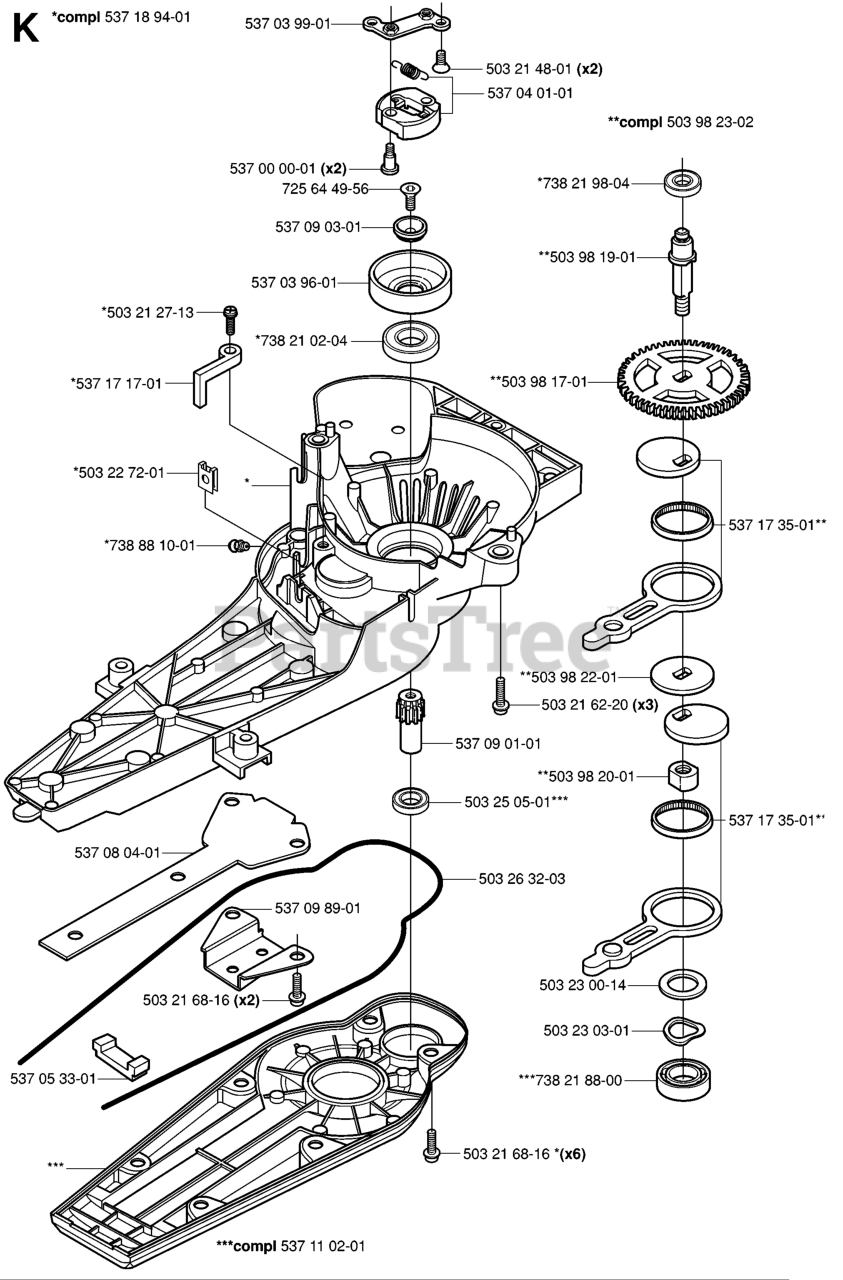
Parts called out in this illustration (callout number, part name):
1	DECK ASSY-WELDMENT
2	RP BOLT 5/16-18 X3/4 ZN/YEL GR
3	BRKT ASM SWAY BAR
4	BRKT DECK SW BAR
5	RETAINER-SPRNG RB
6	REAR SUSP ARM
8	BLADE BOLT
9	LOCKWASHER
10	WASHER.BLADE
11	BLADE 38" V MULCH
12	BEARING.BALL.#6204.(MANDREL)
13	SHAFT ASM VENT
14	HOUSING.MANDREL.VENTED (MACHD)
16	STRIPPER
19	BOLT SHD 5/16-18
21	LOCKNUT
23	BRACKET, DEFLECTOR
24	CAP-SLEEVE LT
25	SPRING TORSION
26	NUT PUSH M
27	SHIELD.DEFLECTOR.MOWER.38.BL
28	Washer 11/32 x 5/8 x 16 Ga SD
29	ROD-HINGE T
30	SCREW THDROL ROLLING WASHER HD
31	WASHER
32	PULLEY MANDREL
33	NUT
36	FLAT IDLER PULLEY
43	CLUTCH ROD SECONDARY
45	RETAINER M
53	BRAKE ASSEMBLY
54	HARDENED WASHER
56	SPACER RETAINER
67	KNOB.CONTROL.7/16
68	V-BELT TRIPATH
69	COTTER PIN
71	CLUTCH ROD
72	RETURN SPRING
73	ARM CLUTCH SECONDARY
77	KEEPER SPRING
78	CLUTCH LEVER ASSY
79	BUSHING.FLANGE.E-RING.GROOVE
80	SPRING-CLUTCH (2 2 PW01)
81	NUT
82	TRUNNION.ADJUSTABLE.3/8-16
86	RUNNER-LH M
87	RUNNER.RH.38
88	WASHER M
89	WASHER GT
92	NUT
96	Bolt, Hex Head 3/8-16 x 1-1/4
97	LOCKNUT
98	WASHER
99	WASHER, LOCK 3/8
101	COVER.MULCHING.38" (2 2)
107	SPACER.IDLER.ARM
108	STIFFENER.IDLER.ARM
109	Bolt Hex Fin 3/8-16 UNC x 2-1/2
110	UPSTOP DECK FRONT 38"
113	SCREW.THDROL.5/16-18X3/4.TTY
122	BRAKE ROD LH
123	BRAKE ROD RH
128	WASHER FELT
129	WASHER
131	BOLT D
141	THRUST WASHER
